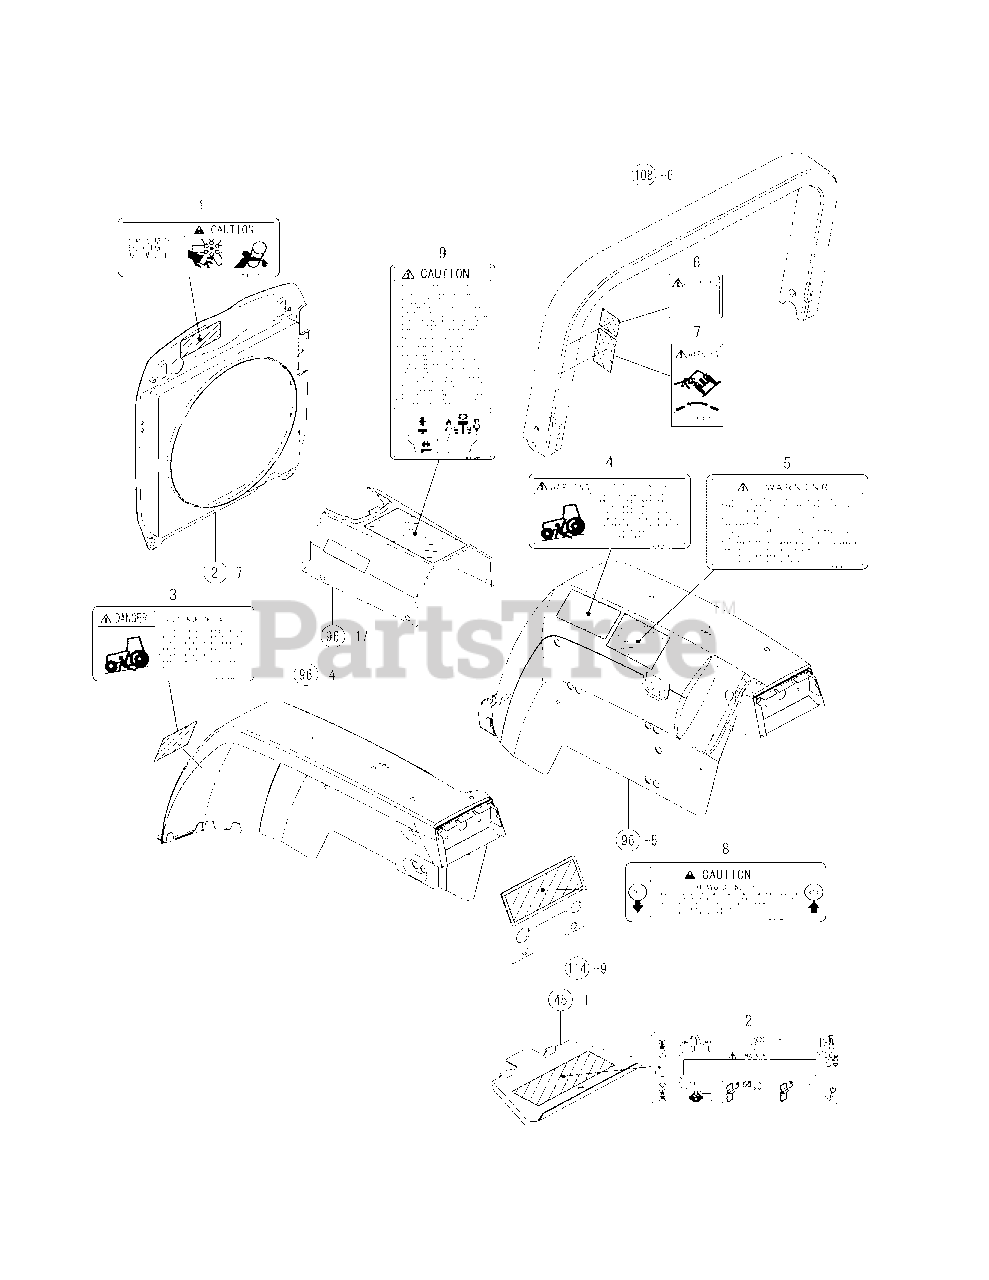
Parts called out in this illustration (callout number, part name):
1	LABEL, CAUTION, FAN
2	LABEL, P.T.O. WARNING
3	LABEL, DANGER, START
4	LABEL, WARNIBG, STOP
5	LABEL, WARNING, ROPS
6	SAFETY DECAL
7	SAFETY DECAL (BELT)
8	LABEL, CAUTION, REAR
9	LABEL, CAUTION
